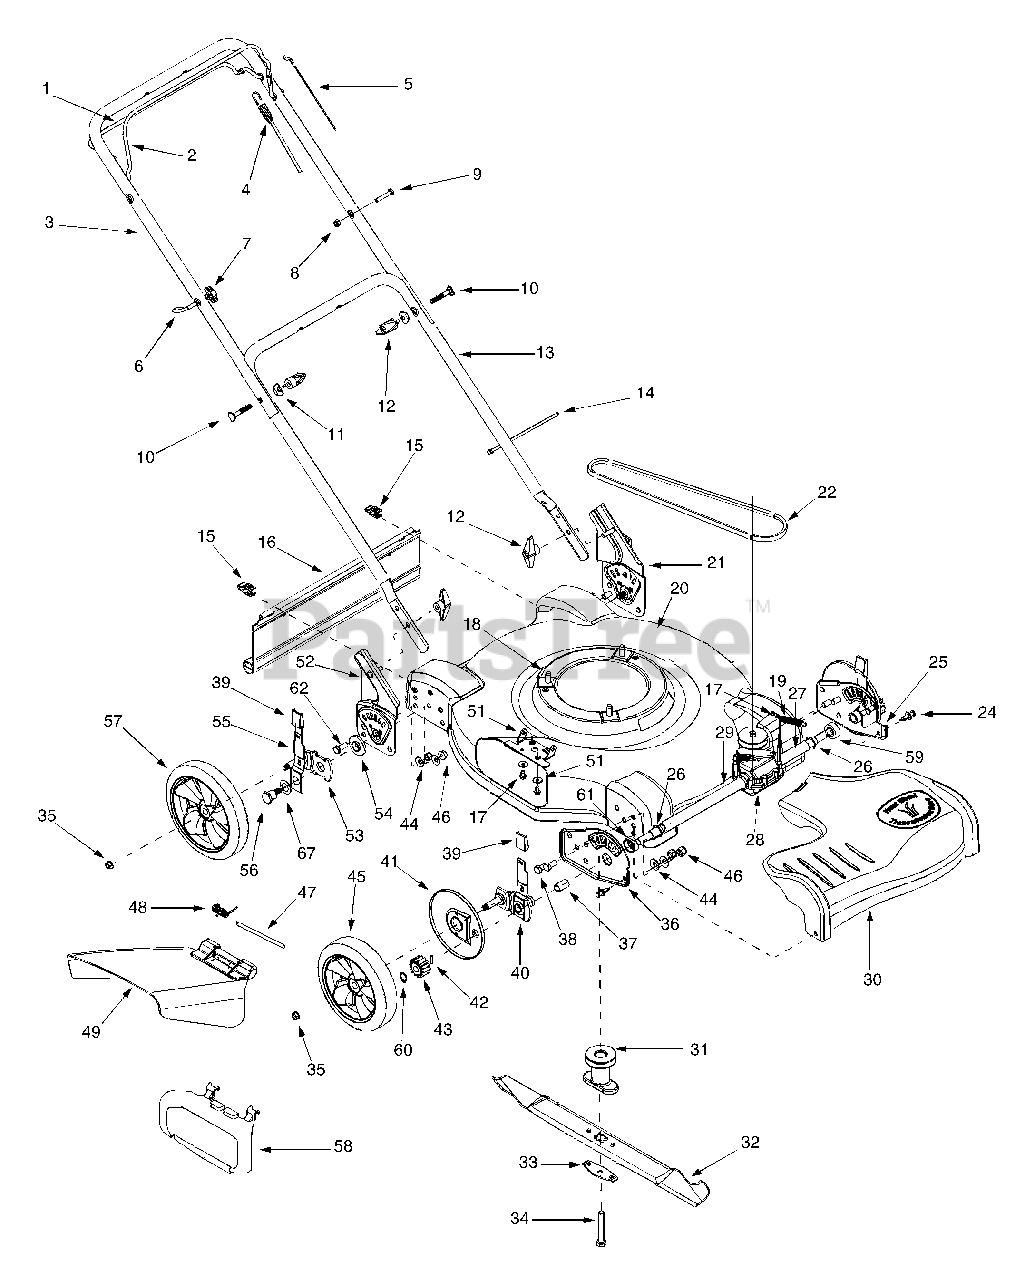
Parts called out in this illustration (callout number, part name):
1	Drive Control Handle
4	Drive Control Cable
5	Blade Control Cable - B&S (40.75")
5	Blade Control Cable - B&S (37.75")
5	Blade Control Cable - B&S (50.56")
6	Eye Bolt
7	Wing Nut 1/4-20
8	Hex Lock Nut 1/4-20
9	Hex Cap Screw 1/4-20x 1.5
10	Carriage Bolt 5/16-18 x 2.0
11	Shoulder Washer .320 ID x .93 OD
12	Wing Nut 5/16-18
14	Cable Tie
15	Hinge Clip
16	Trail Shield
17	Self-Tap Screw 1/4-20x.5" lg
18	Hex Washer Screw 3/8-16 x 1.0
19	Spring .47 OD x 2.50
22	V-Belt
23	Hex Washer Screw 1/4-20 x .500
24	Rivet
26	Retainer Ring
27	Sleeve Spacer .550 ID X 3.30
28	Transmission Assembly Complete
29	Sleeve Spacer .550 ID x7.95
30	Transmission Cover
31	Blade Adapter, One Piece
32	Mulching Blade 22"
33	Bell Washer
34	Hex Cap Screw 3/8-24 x 1.5
35	Lock Nut 3/8-16
37	Sleeve Bearing
38	Hex Cap Screw 3/8-16 x .75
39	Adjustment Knob
40	Spring Lever Assembly - LH* (FWD)
40	Spring Lever Assembly - RH* (FWD)
41	Wheel Dust Cover
42	Pin
43	Spur Gear 14T - LH
43	Spur Gear 14T - RH
44	Washer Spacer .401 ID x .870 OD
45	Front Wheel Assembly 8 x 1.8
46	Hex Lock Nut 3/8-16
47	Hinge Pin
48	Torsion Spring
49	Side Discharge Assembly
50	Bell Washer .265 ID x .75 OD
51	Chute Hinge
51	Washer, Bell 1/4" I.D.
54	Height Adjustment Bearing
55	Spring Lever
56	Shoulder Screw 3/8-16
57	Rear Wheel 8 x 1.8
58	Snap Mulching Plug (If Equipped)
59	Bearing Spacer
60	Snap Ring.500
61	Bell Washer.760 ID x 1.25 OD
62	Hex Cap Screw 3/8-16 x 1.0
